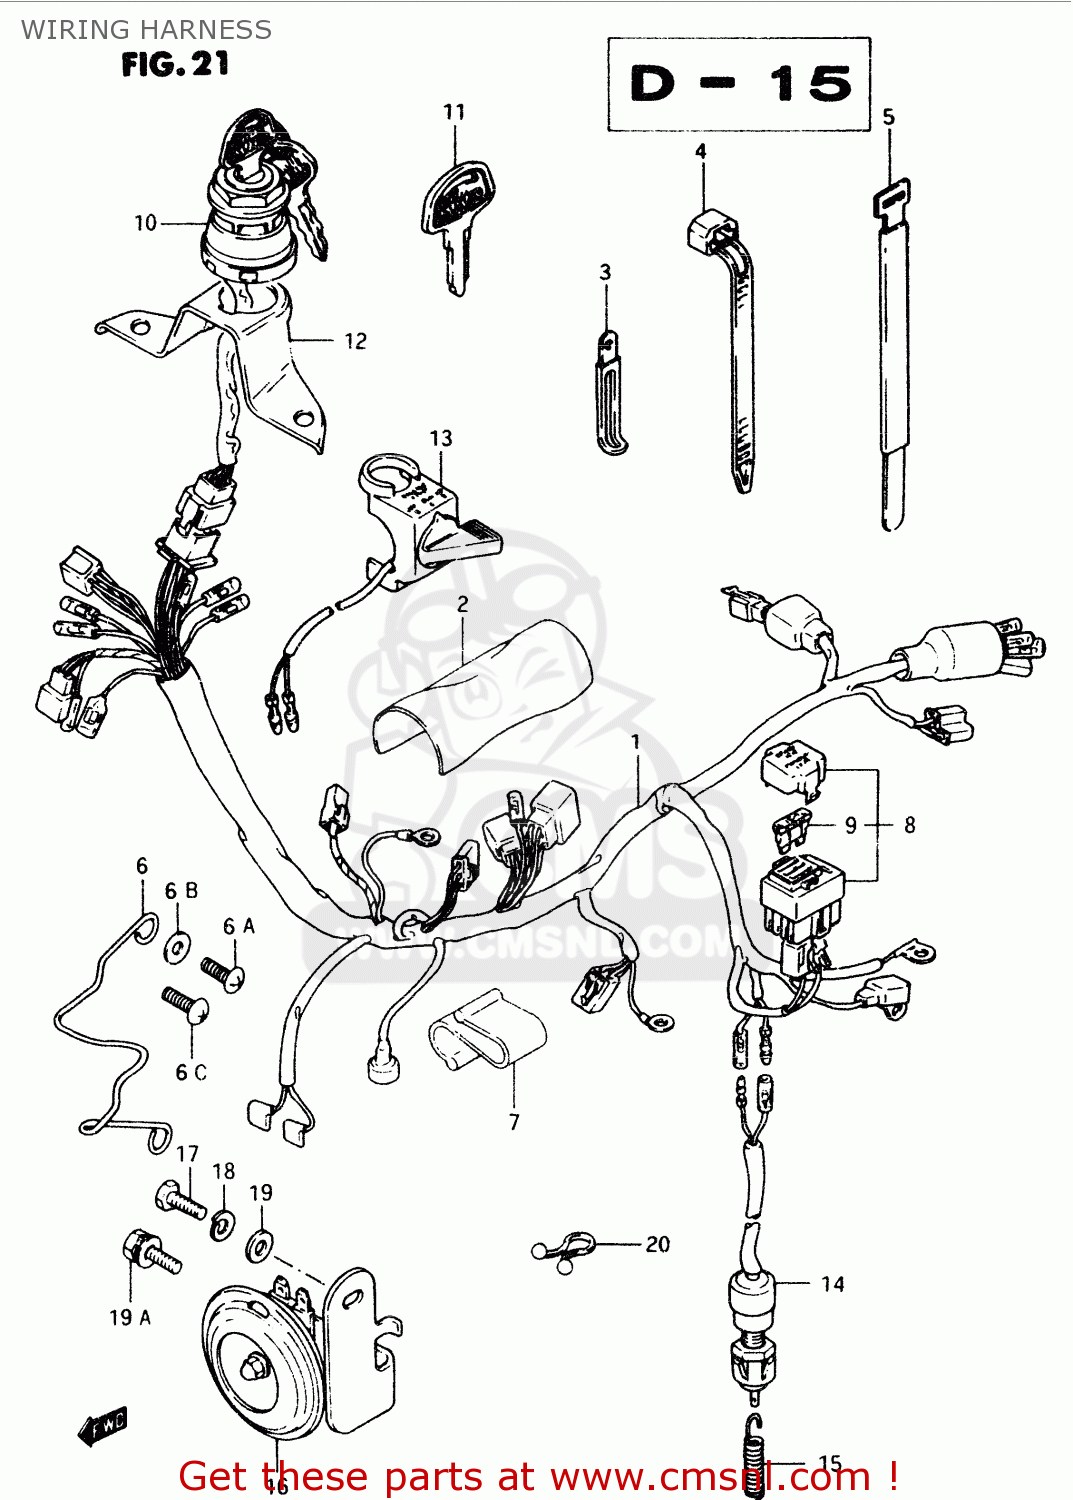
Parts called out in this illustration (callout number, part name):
1	HARNESS,WIRING
2	COVER, HARNESS
3	CLAMP
4	CLAMP,L:88
5	CLAMP(L:250)
6	GUIDE,WIRING HARNESS
6A	SCREW
6B	WASHER
6C	SCREW 6X12
7	HOLDER, WIRING HARNESS
8	BOX ASSY,FUSE
9	FUSE(15A)
10	SWITCH ASSY,IGNITION
11	KEY,BLANK
12	BRACKET,IGNITION SWITCH
13	SWITCH ASSY,ENGINE STOP
14	SWITCH ASSY,STOP LAMP
15	SPRING
16	HORN ASSY
17	BOLT
18	WASHER,LOCK
19	WASHER
19A	BOLT
20	CLIP
